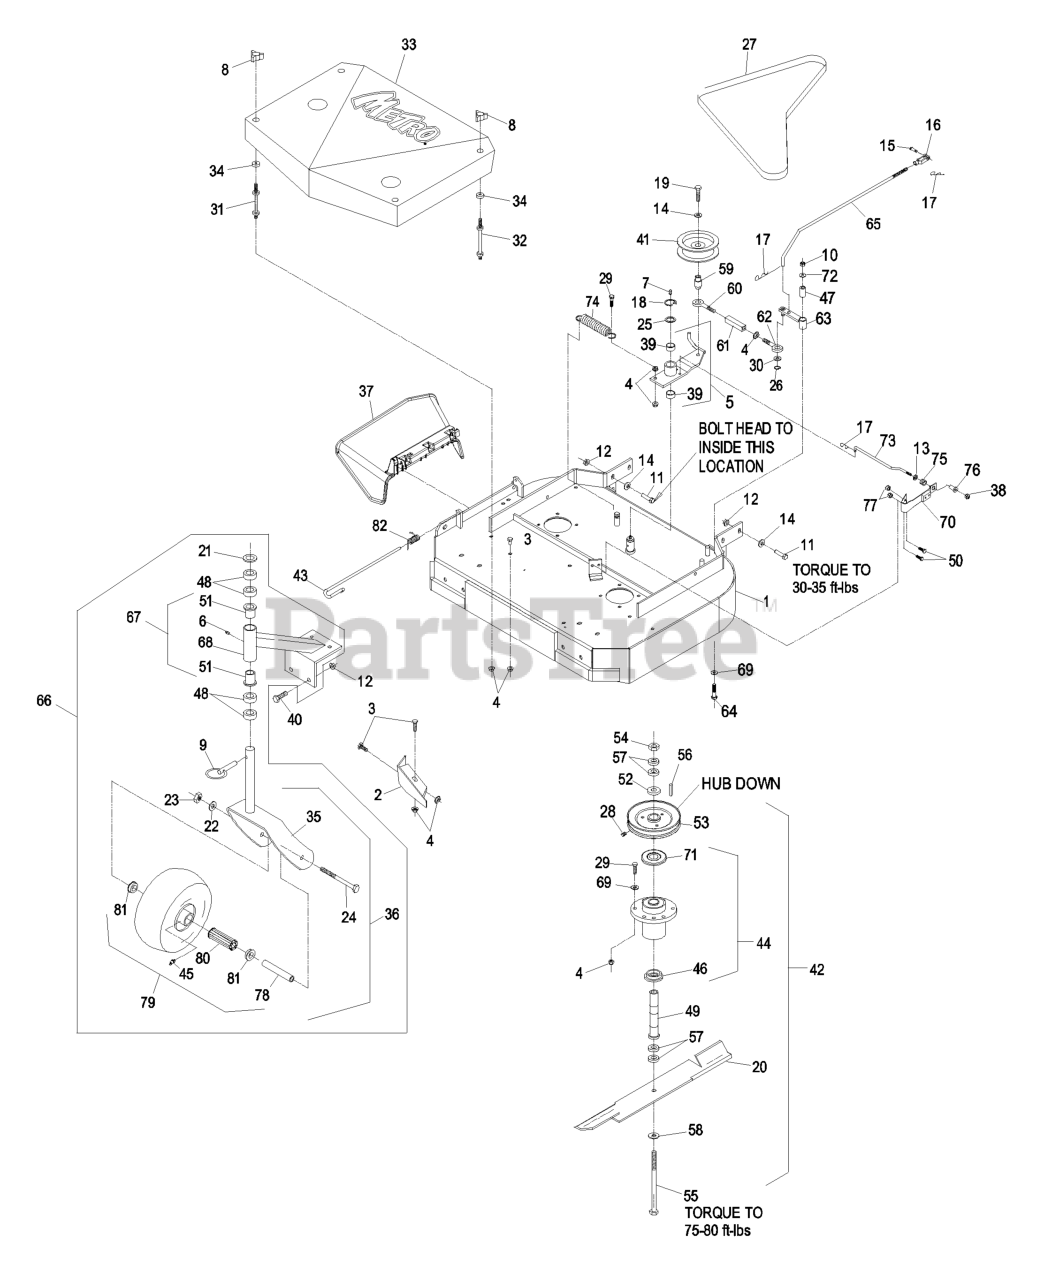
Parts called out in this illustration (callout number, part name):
1	ASM,DECK 36 RIGID
2	BAFFLE-DOGLEG
3	SCREW-HH
5	IDLER ARM ASM
6	FITTING-GREASE
7	FITTING-GREASE
8	KNOB-3 PRONG
10	NUT-LOCK, NI
11	SCREW-HH
12	NUT-HHF, WHIZ
13	RING-PUSH ON
14	WASHER-BELLEVILLE
15	PIN-CLEVIS
16	YOKE-ADJUSTABLE
17	PIN-COTTER
18	RING-RETAINING, EXT
19	SCREW-HH
21	WASHER-FLAT
22	WASHER-LOCK
23	NUT-HH
24	SCREW-HH
25	WASHER-SPINDLE
26	RING-RETAINING, EXT
27	BELT,BLADE METRO 36
28	SCREW-SET
29	SCREW-HH
30	WASHER-PLAIN
31	STUD-SHIELD, BELT (SHORT)
32	STUD-SHIELD, BELT (LONG)
36	ASM,CASTER/WHEEL
37	CHUTE DEFLECTOR XRK M056
38	NUT-LOCK, NI
39	SLEEVE-BEARING
40	SCREW-HH
42	ASM, CUTTER HOUSING OUTER
43	PIN-CHUTE
44	KIT, CUTTER HOUSING
45	FITTING-GREASE
46	SPACER-GUARD, BOTTOM
47	TUBE-PIVOT
48	SPACER-CASTER
49	TUBE-SPINDLE, SHORT
50	SCREW-HH
51	BEARING-FLANGED
52	WASHER-RETAINER, SHEAVE
53	SHEAVE
54	NUT-HEX
55	SCREW-CAP, HH
58	WASHER-SPRING
59	BUSHING-ENGAGEMENT
60	EYEBOLT-THREAD, LH
61	BODY-TURNBUCKLE
62	EYEBOLT-THREAD, RH
63	ARM-ASSIST, 32/36
64	SCREW-HH
65	ARM-ASSIST, LINKAGE
66	ASM,CASTER/MOUNT
67	SUPPORT ASM
69	WASHER-SPRING
70	PAD AND SPRING ASM
71	GUARD-BEARING, TOP
72	WASHER-FLAT
73	ROD-BRAKE
74	SPRING-EXTENSION
75	SPRING-COMPRESSION
76	SPACER-FLANGED
77	NUT-LOCK, NI
79	KIT, SP CASTER WHEEL REPL
80	BEARING
81	BUSHING
82	SPRING, TORSION
